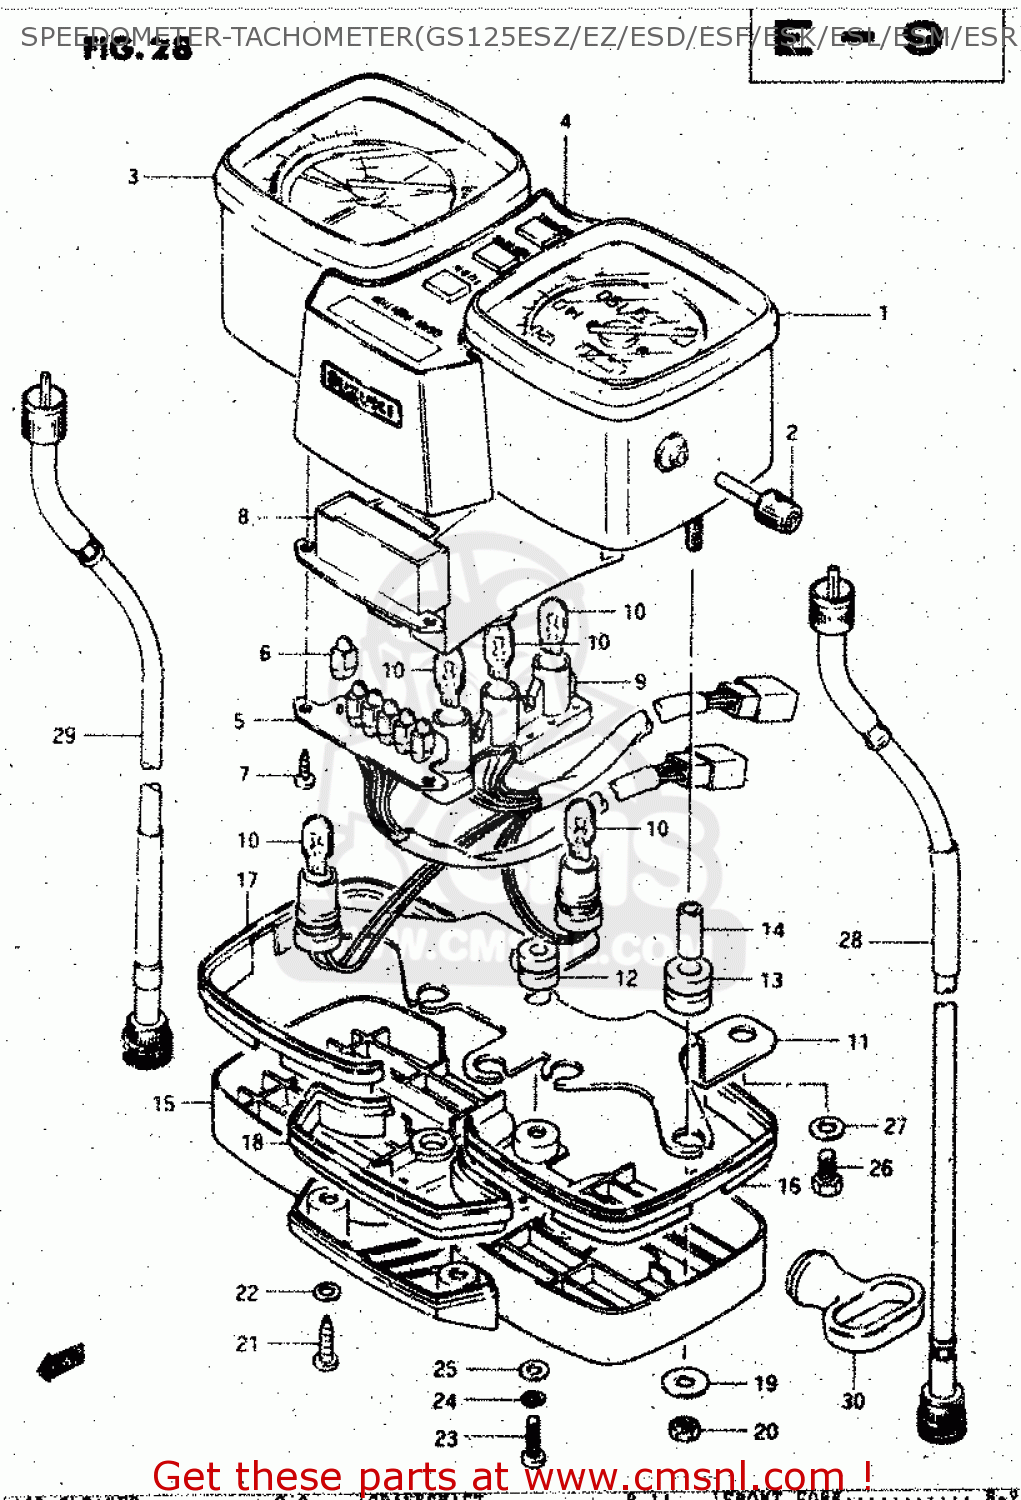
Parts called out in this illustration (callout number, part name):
1	SPEEDOMETER(KILO)
2	KNOB,TRIP
3	TACHOMETER
4	CASE,PILOT BULB
5	INDICATOR,GEAR POSITION
6	BULB(14V1.12W)
7	SCREW(3X12)
8	CASE,PILOT BOX INNER
9	SOCKET,PILOT LAMP
10	BULB(12V3.4W,T10,BF175-01450A)
11	BRACKET
12	CUSHION,PILOT BOX
13	CUSHION,METER
14	SPACER
15	COVER,LWR
16	MOULDING, SPEEDOMETER
17	MOULDING, TACHOMETER
18	MOULDING, PILOT BOX
19	WASHER
20	NUT
21	SCREW 4X16
22	WASHER 4MM
23	SCREW
24	WASHER,LOCK
25	WASHER 4MM
26	BOLT
27	WASHER
28	CABLE ASSY,SPEEDOMETER
29	CABLE, TACHOMETER
30	GUIDE,CABLE
